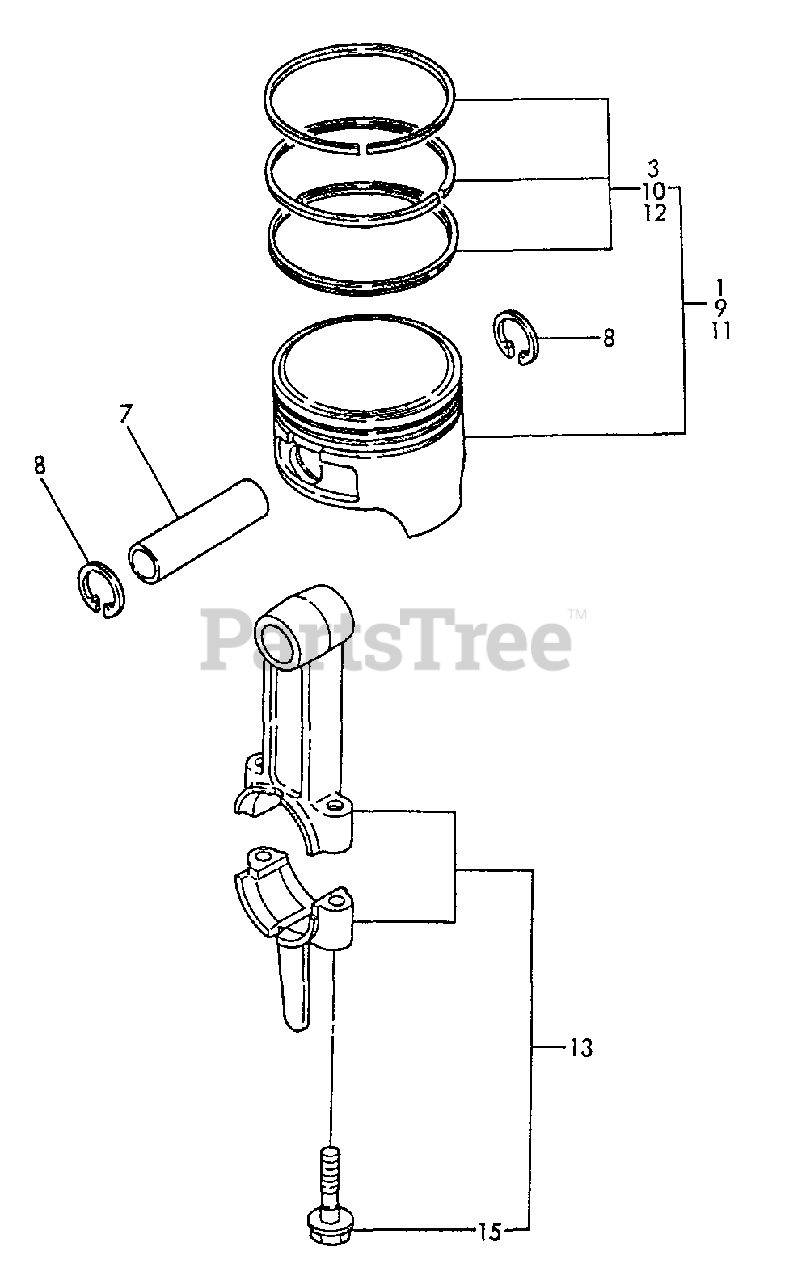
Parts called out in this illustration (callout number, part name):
1	PISTON ASSY
3	PISTON RING ASSY
7	PIN, PISTON
8	RING, RETAINING - 16
9	PISTON ASSY O.S.=0.25
10	RING ASSY O.S.=0.25
11	PISTON ASSY O.S.=0.5
12	RING ASSY O.S.=0.5
13	CONNECTING ROD ASSY
15	BOLT, ROD
